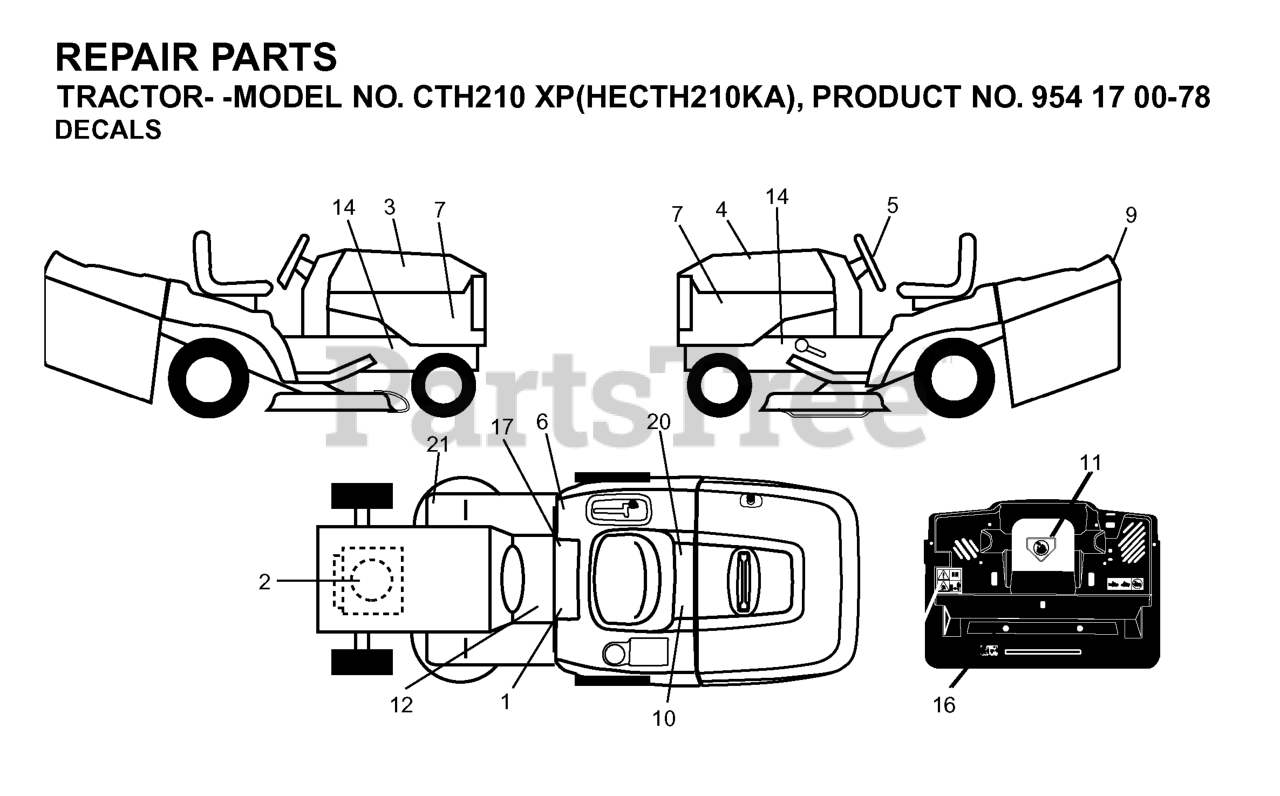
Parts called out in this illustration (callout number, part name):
1	DECAL READ OWNER'S MAN SYMS
5	DECAL.WHEEL.STEERING.HUSQ.PERM
6	Decal, Fender 100 DB/CE
9	DECAL FENDER HUSQ
10	DECAL BTRY SYMBOLS
11	DECAL.INTERNATIONL.CUTFINGER
12	DECAL
16	DECAL
17	DECAL PARK BRAKE
20	DECAL.BYPASS.FENDER.CRD.LT.YT
